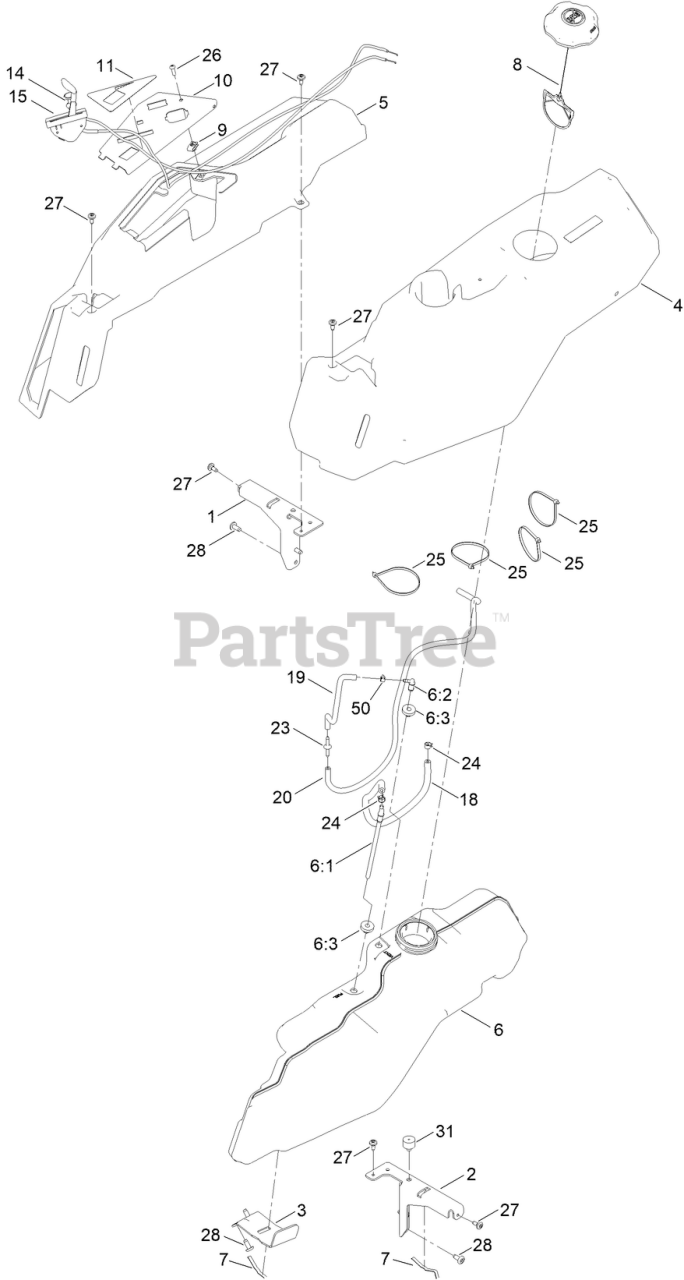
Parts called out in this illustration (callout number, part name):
1	SUPPORT-POD, RH
2	SUPPORT-POD, LH
3	SUPPORT-TANK, FUEL
4	POD-LH
5	POD-RH
6	TANK-FUEL ASM
6:1	CONNECTOR-ELBOW, 90 DEG
6:2	FITTING-ELBOW 90
6:3	BUSHING
7	SPRING
8	CAP-FUEL, RATCHETING
10	PANEL - CONTROL
11	DECAL-PANEL CONTROL
14	CABLE-THROTTLE
15	CABLE-CHOKE
18	HOSE-FUEL
19	HOSE-FUEL
20	HOSE-FUEL
23	ADAPTER ORIFICE
24	CLAMP-HOSE
25	TIE-CABLE
26	SCREW-PRH
27	SCREW-SHOULDER
31	BUMPER-GROMMET
50	CLAMP-HOSE
